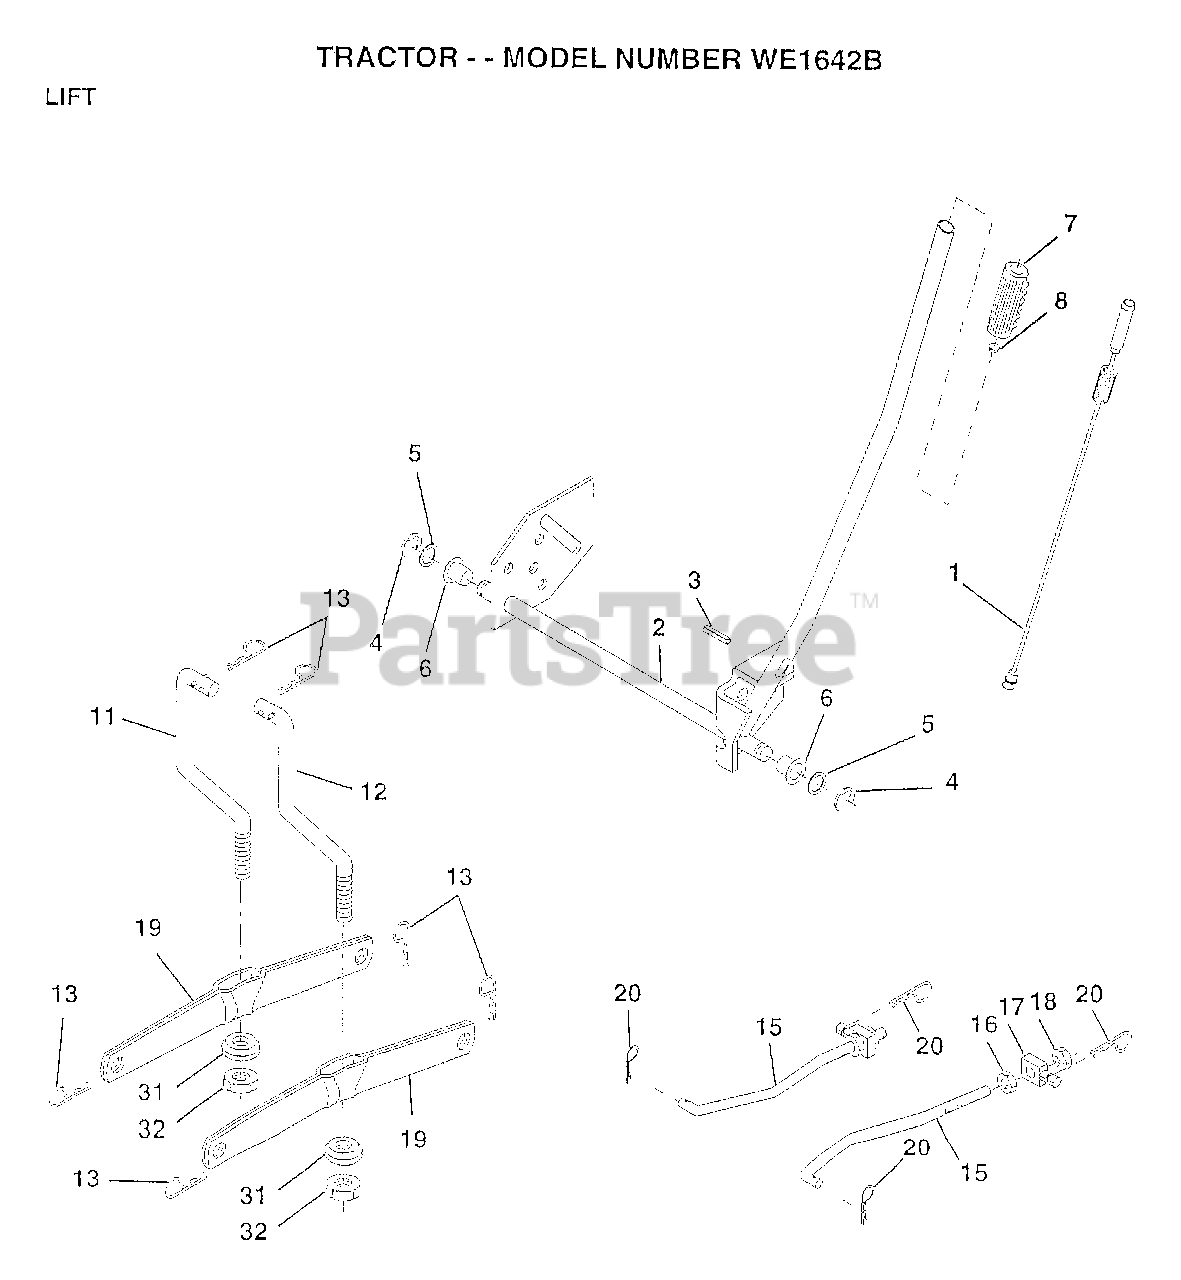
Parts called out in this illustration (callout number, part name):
1	WIRE ASM W.SPRING
2	"SHAFT ASM LIFT,RH"
3	PIN-GROOVE LT
5	WASHER
6	NYLON BEARING
7	GRIP
15	LINK.FRONT
16	NUT
17	TRUNION
18	NUT.LK.W/WSH.1/2.
19	ARM SUSP REAR
20	RETAINER.SPRING
31	BEARING PVT LH
32	NUT.CROWNLOCK.3/8
